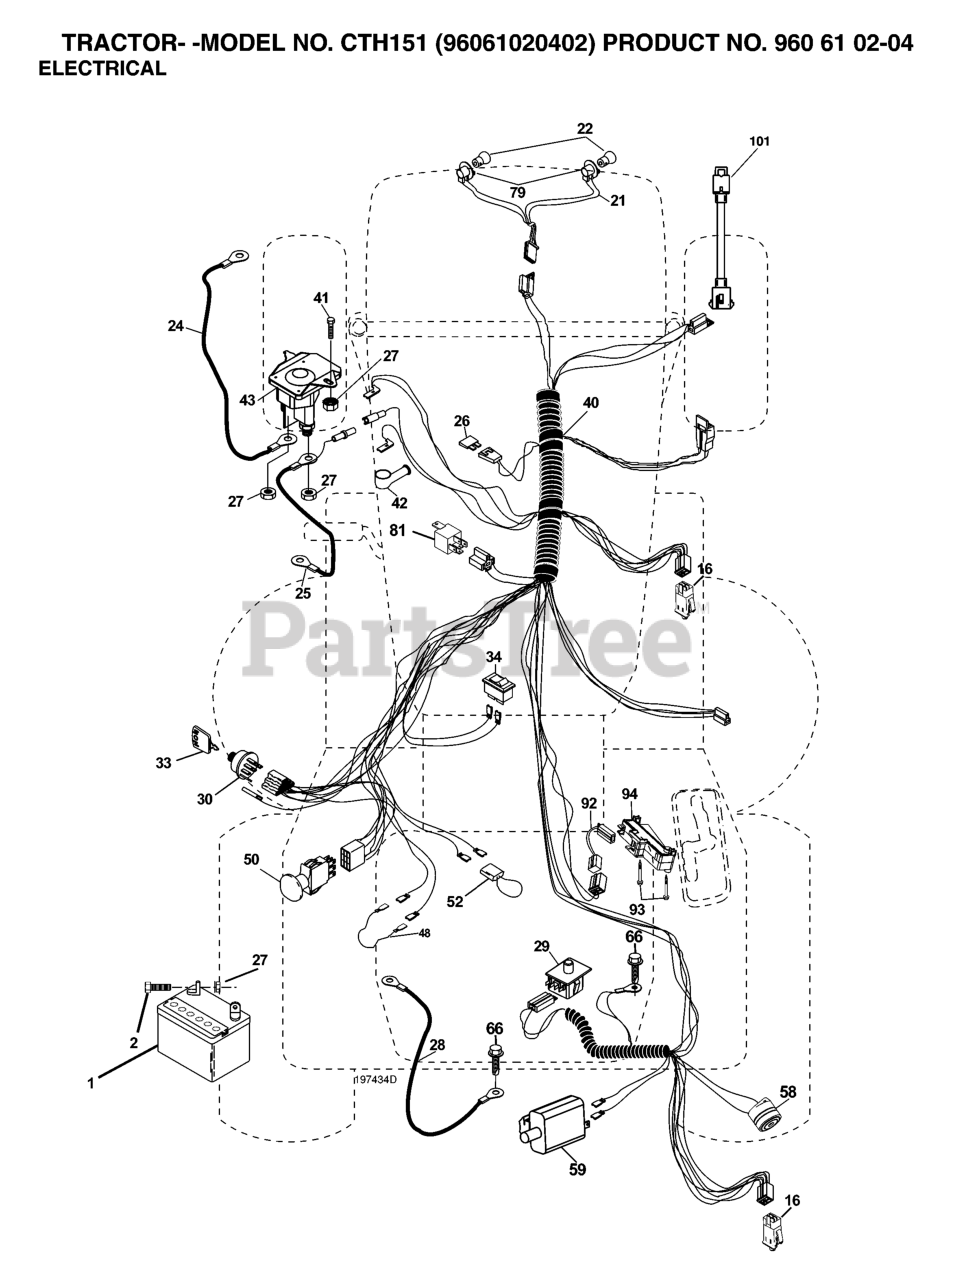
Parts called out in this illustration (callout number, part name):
1	BATTERY 12V .35 AMP
2	BOLT.HEX.1/4.X.3/4.DICHROMATE
16	SWITCH INTERLOOK PUSH-IN
21	HARNESS.LIGHT W/4152J BULBS
24	BATTERY CABLE GT
25	CABLE BATTERY
26	FUSE 20AMP
27	NUT
28	CABLE GROUND
29	SWITCH.SEAT.DP W/RAMPS
30	SWITCH.IGN.DELTA.W.LGH.ROS
33	KEY MLD GEN DELTA
40	RP HARNESS.IGN.ELECT.REG.CRD
41	BOLT
42	TERMINAL COVER
43	SOLENOID.W/BRASS.PLUNGER
48	ADAPTER.AMMETER
50	RP.PTO.SWITCH.8 TERMINAL.BLACK
52	WIRE PROTECTION LOOP
58	BUZZER
59	.WITCH.FULL BAGGER.INDICATOR
79	BULB HOLDER ASM.
81	RELAY.ASSY.T
92	HARNESS.PIGTAIL.CONSLE
93	SCREW.PLASTITE
94	MODULE.REVERSE.ROS
101	PIGTAIL.MATNLK.NEW.HAR
